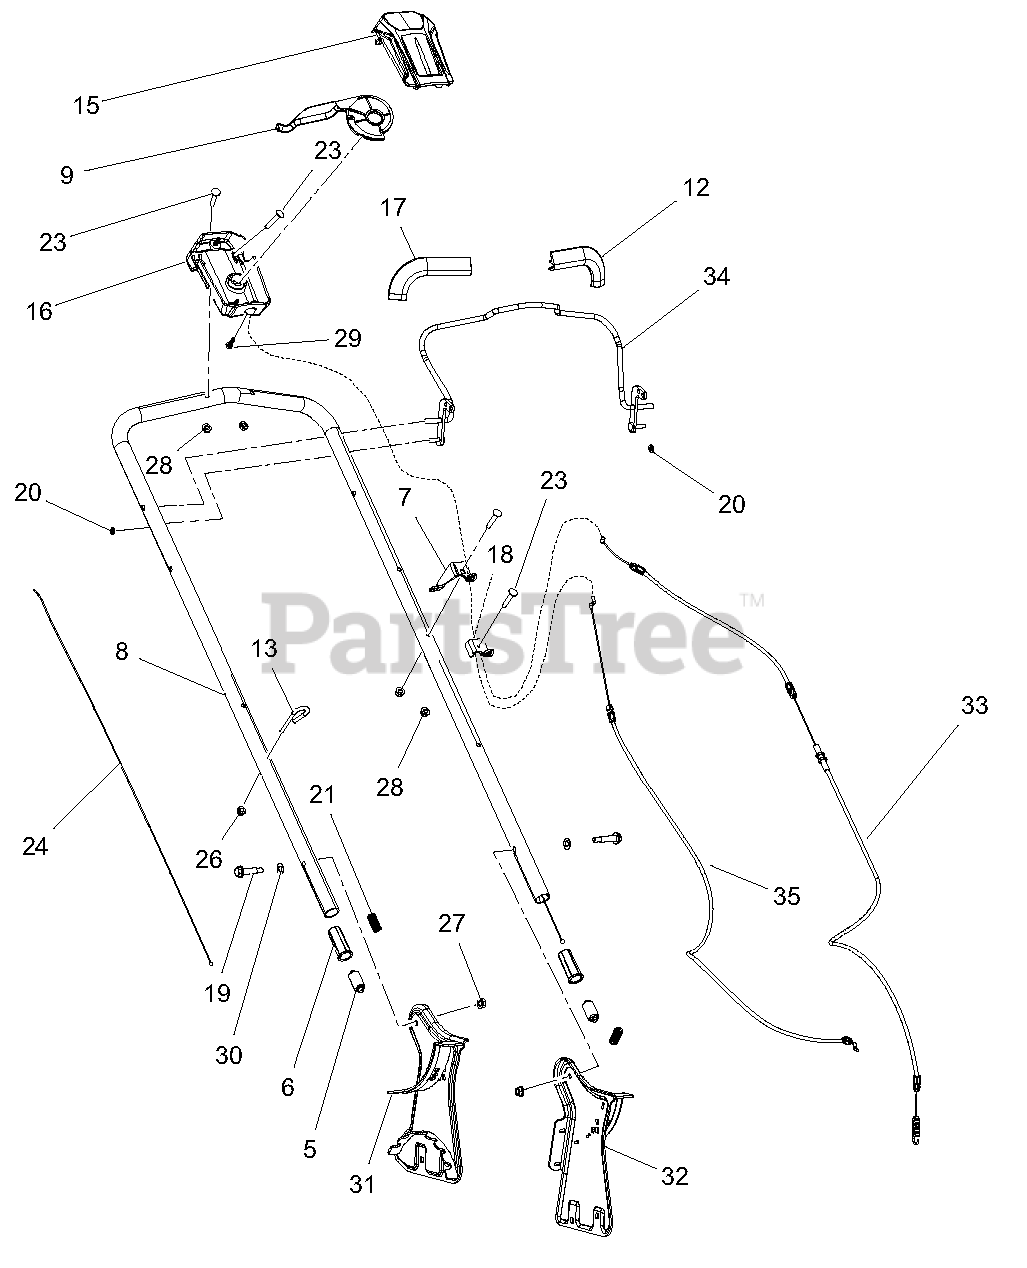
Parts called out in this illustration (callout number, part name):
5	PIN, LM HANDLEBAR LOCKING
6	HANDLEBAR ADJUSTMENT INSERT
7	BRKT, CABLE ANCHOR
8	HANDLEBAR,
9	HANDLE, DRIVE CONTROL
12	GUARD, FINGER - LH
13	GUIDE, RECOIL ROPE
15	HOUSING, UPPER DRIVE CONTROL
16	FRONT SQUEEZE BOX
17	HAND GRIP WITH DECAL
18	BRKT, CABLE - DRIVE
19	BLT, SHLDR .50 X 1.30 X .38-16
20	PUSH-NUT 1/4
21	SPRG, COMPRESSION
23	BLT-RDHDSQNK-GR5-Y
24	ADJUSTABLE HANDLEBAR CABLE
26	NUT-LK-NYL-FLG .25-20 YWZC
27	NUT,LK-TOP-FLG
28	NUT-HEX TOP LOCK FLG
29	SCR-TAP #12-14X.75 PLASTITE BLZC
30	WSHR-FL-STL .385x.745x.030 YWZC
31	WLDMT, RH SIDE PLATE
32	WLDMT, LH SIDE PLATE
33	CABLE, DRIVE CONTROL
34	BAIL, OPC
35	CABLE, OPC
